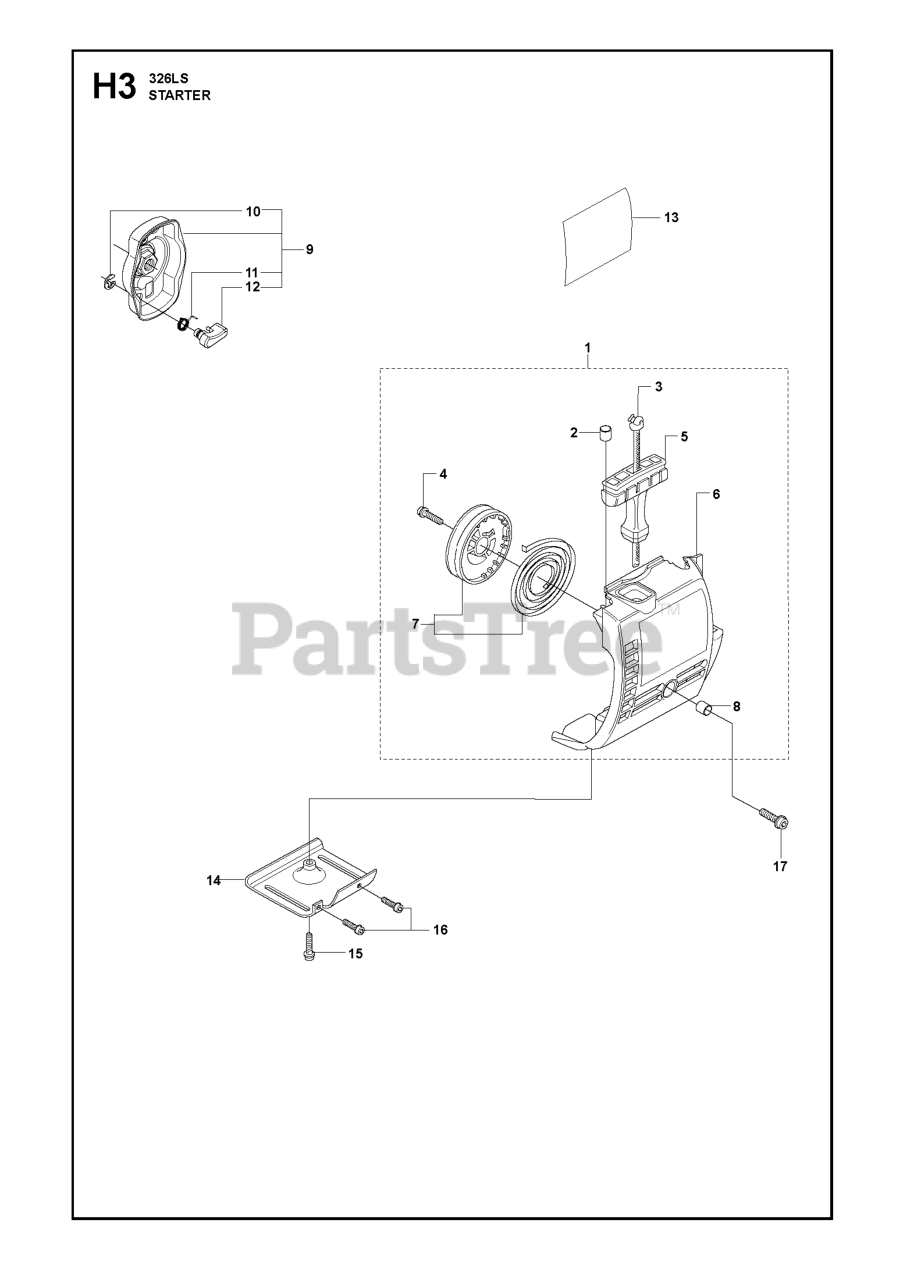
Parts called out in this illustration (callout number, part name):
1	STARTER ASSY
2	SPACING SLEEVE
3	STARTER ROPE
5	STARTER HANDLE
6	RP STARTER HOUSING
7	STARTER PULLEY ASSY.
8	SPACING SLEEVE
9	STARTER PAWL BRIDGE
12	STARTER PAWL
13	STARTER DECAL 326LS
15	SCREW
17	SCREW
